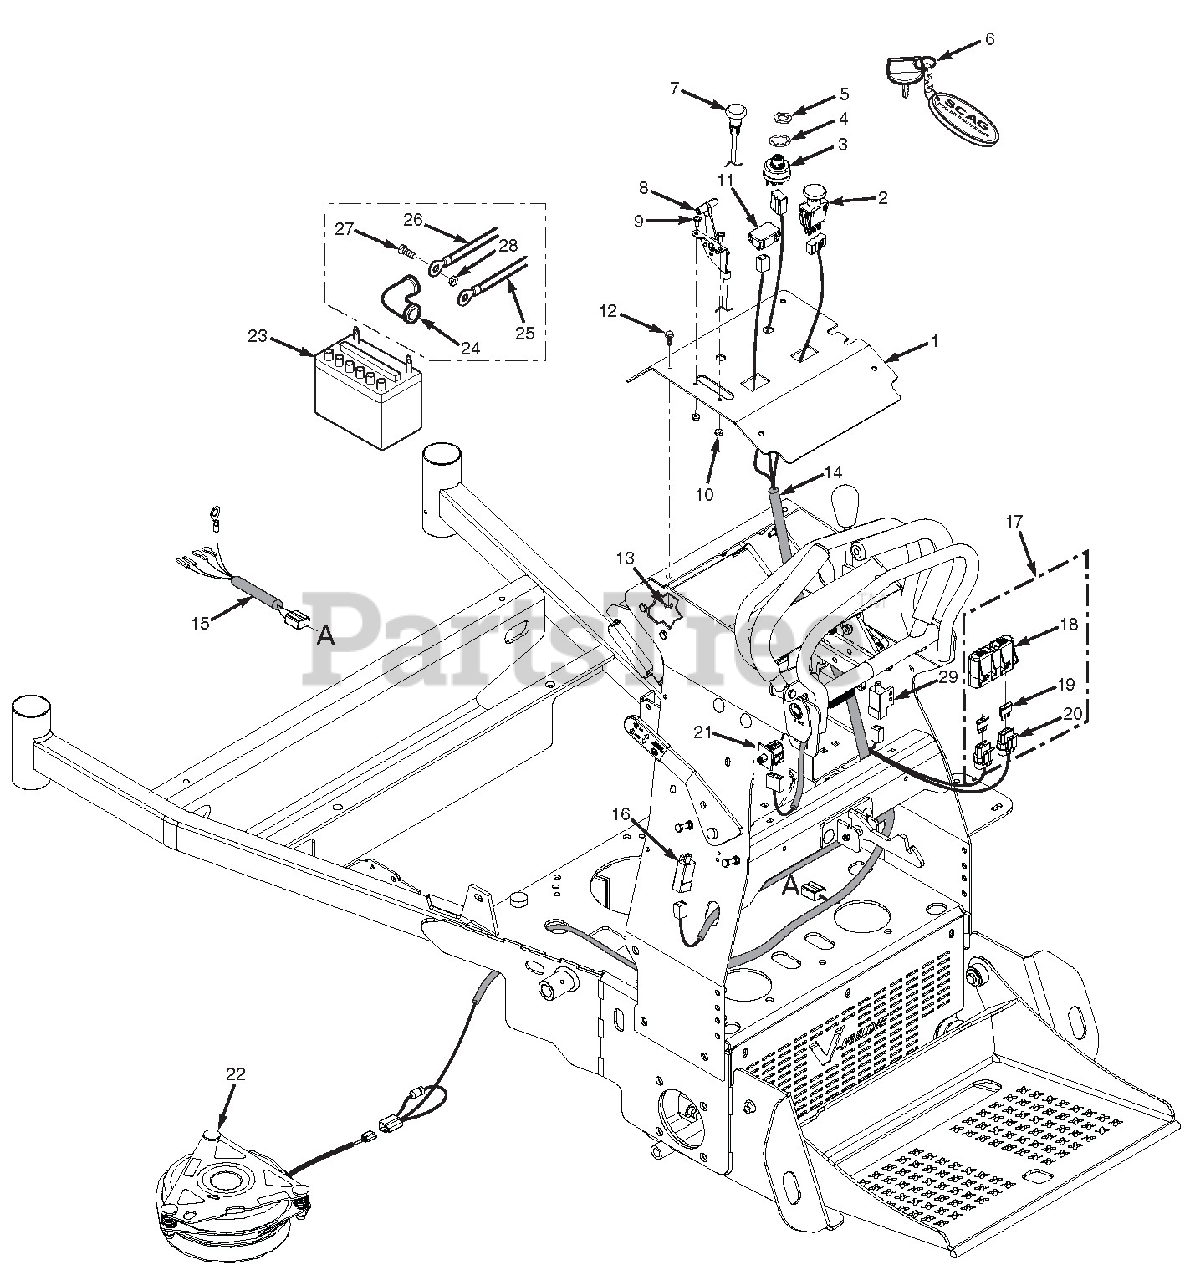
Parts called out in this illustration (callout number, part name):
1	Instrument Panel w/Decal
2	Switch, PTO - 10 Amp
3	Key Switch
4	Lockwasher, 5/8" Internal Tooth
5	Nut, 5/8-32 Special
6	Key Chain w/ Keys
6	Key w/Shroud
7	Choke Control, SVR
8	Throttle Control, SVR
9	Bolt, Carriage #10-24 x 1/2"
10	Locknut, #10-24
11	Hourmeter
12	Bolt, Hex Head 1/4-20 x .63
13	Nut, Serrated Flange 1/4-20
14	Wire Harness, SVR
15	Wire Harness Adapter, Kawasaki
16	Switch, Interlock
17	Double Fuse Assy.
18	Cover, Sealed Double
19	Fuse, 20 Amp
20	Fuse Holder
21	Switch, Double Pole - Plunger
22	Clutch w/Tag (36A, 48V, 52V)
22	Clutch w/Tag (61V)
23	Battery (not avail. through Scag)
24	Rubber Boot
25	Cable, Battery Black 18"
26	Cable, Battery Red 18"
27	Bolt, Hex Head 1/4-20 x 3/4"
28	Nut, 1/4-20
29	Switch, Interlock
